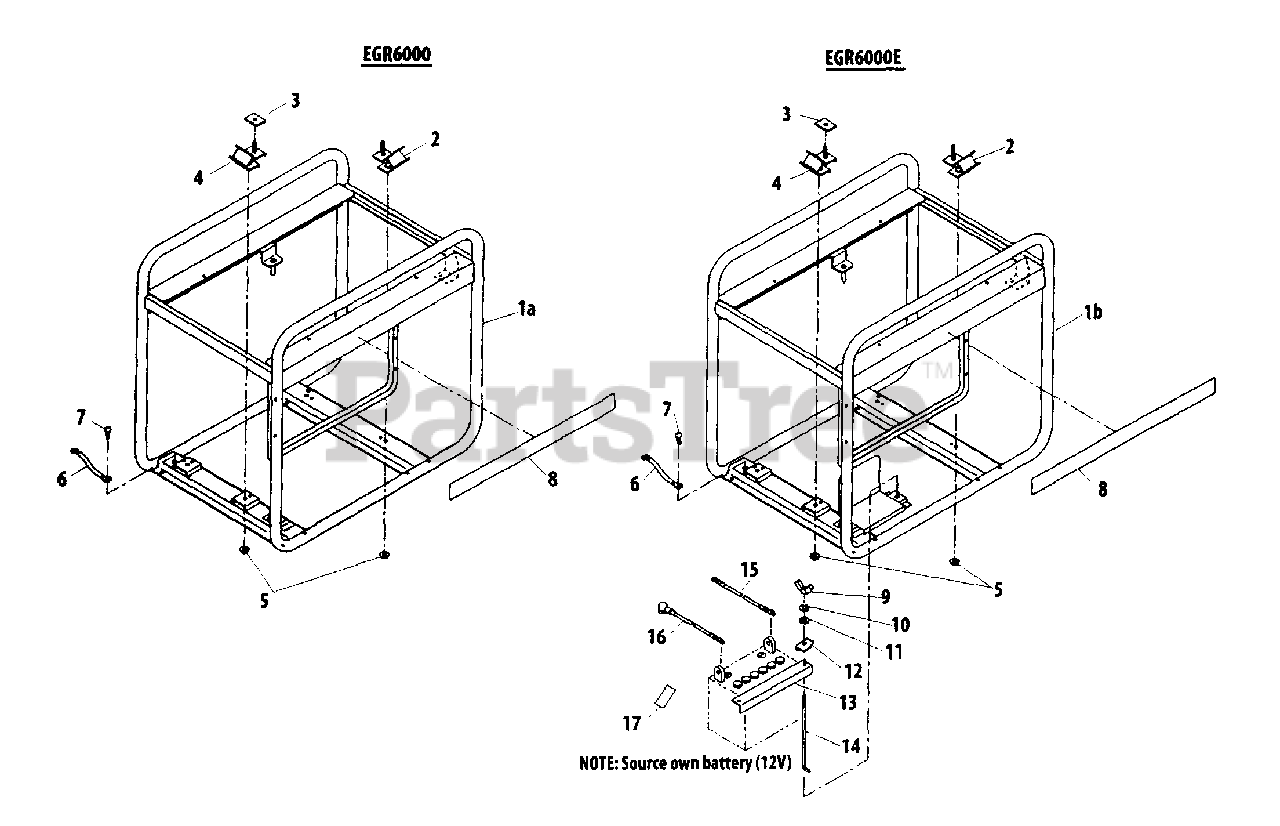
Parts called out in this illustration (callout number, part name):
1A	FRAME
1B	FRAME
5	NUT - FLANGE
8	LABEL - MODEL
9	WINGNUT
10	WASHER, SPRING 6
11	WASHER 6.5×13×1
12	SPACER
13	STAY, BATTERY
14	BOLT, BATTERY
15	WIRE
16	WIRE
17	LABEL
